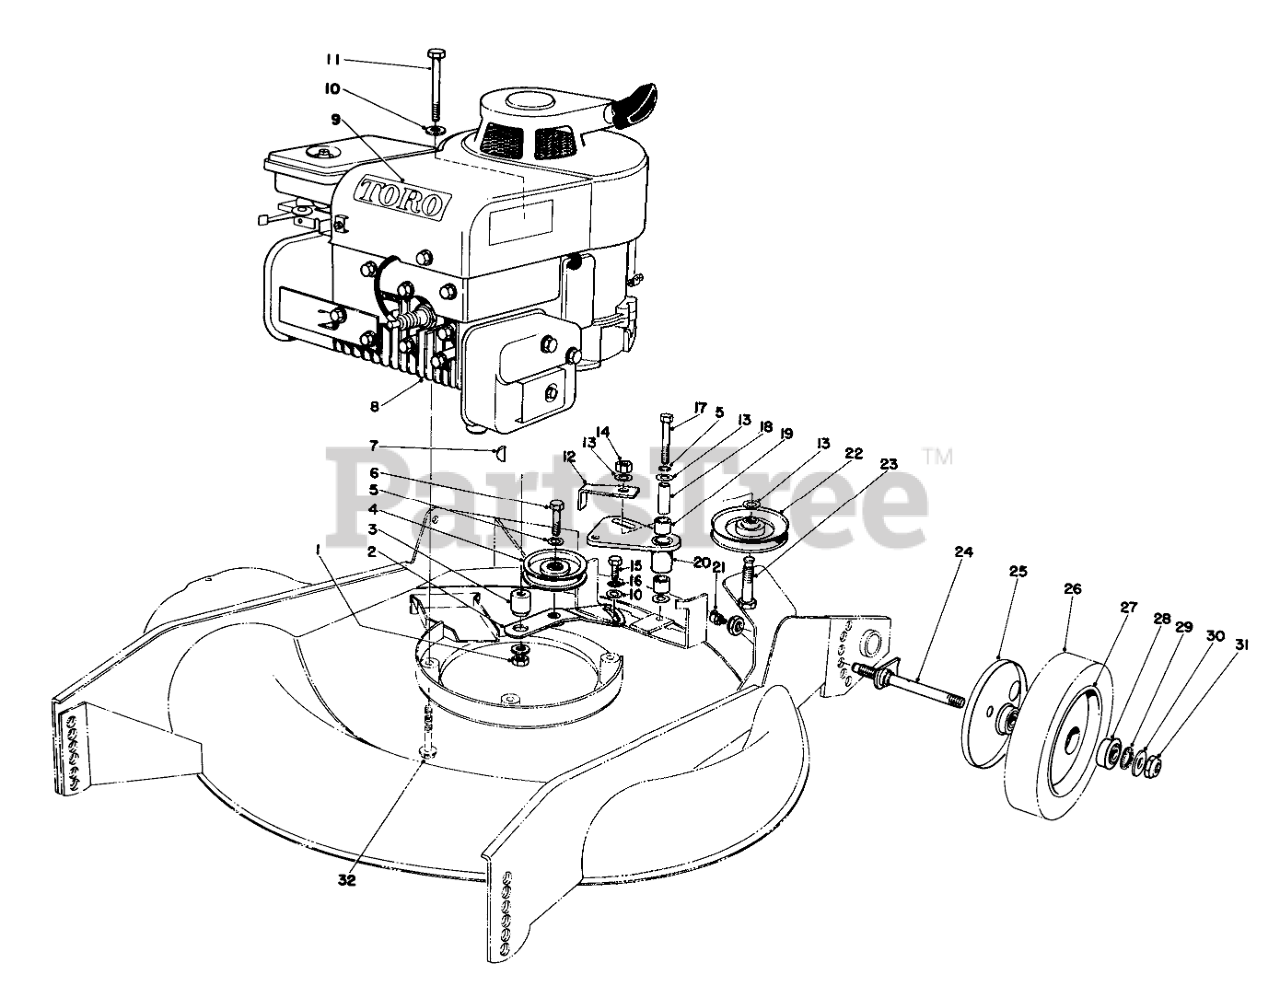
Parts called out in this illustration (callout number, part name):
1	Nut
2	Idler Arm
3	Spacer-Idler Arm
4	PULLEY-IDLER
5	WASHER-LOCK
6	SCREW-HH
7	KEY-WOODRUFF
8	Engine
9	Decal Toro
10	WASHER-PLAIN
11	SCREW-HH
13	WASHER-FLAT
14	Nut
15	SCREW-HH
16	WASHER-LOCK, INTERNAL
17	SCREW-HH
18	ROLLED SPACER
19	BUSHING
20	Idler Arm (Incl. Ref. #19)
21	GREASE FITTING
22	IDLER PULLEY R
23	Screw
24	Spindle (Incl. Ref. #21)
25	WHEEL COVER
27	Wheel & Tire Assembly Rear (Incl. Ref. #26 & 28)
28	BEARING-BALL
29	FELT WASHER
30	WASHER-FLAT
31	NUT-LOCK, NI
32	3/8-16 X 2-3/4 CAPSCR
